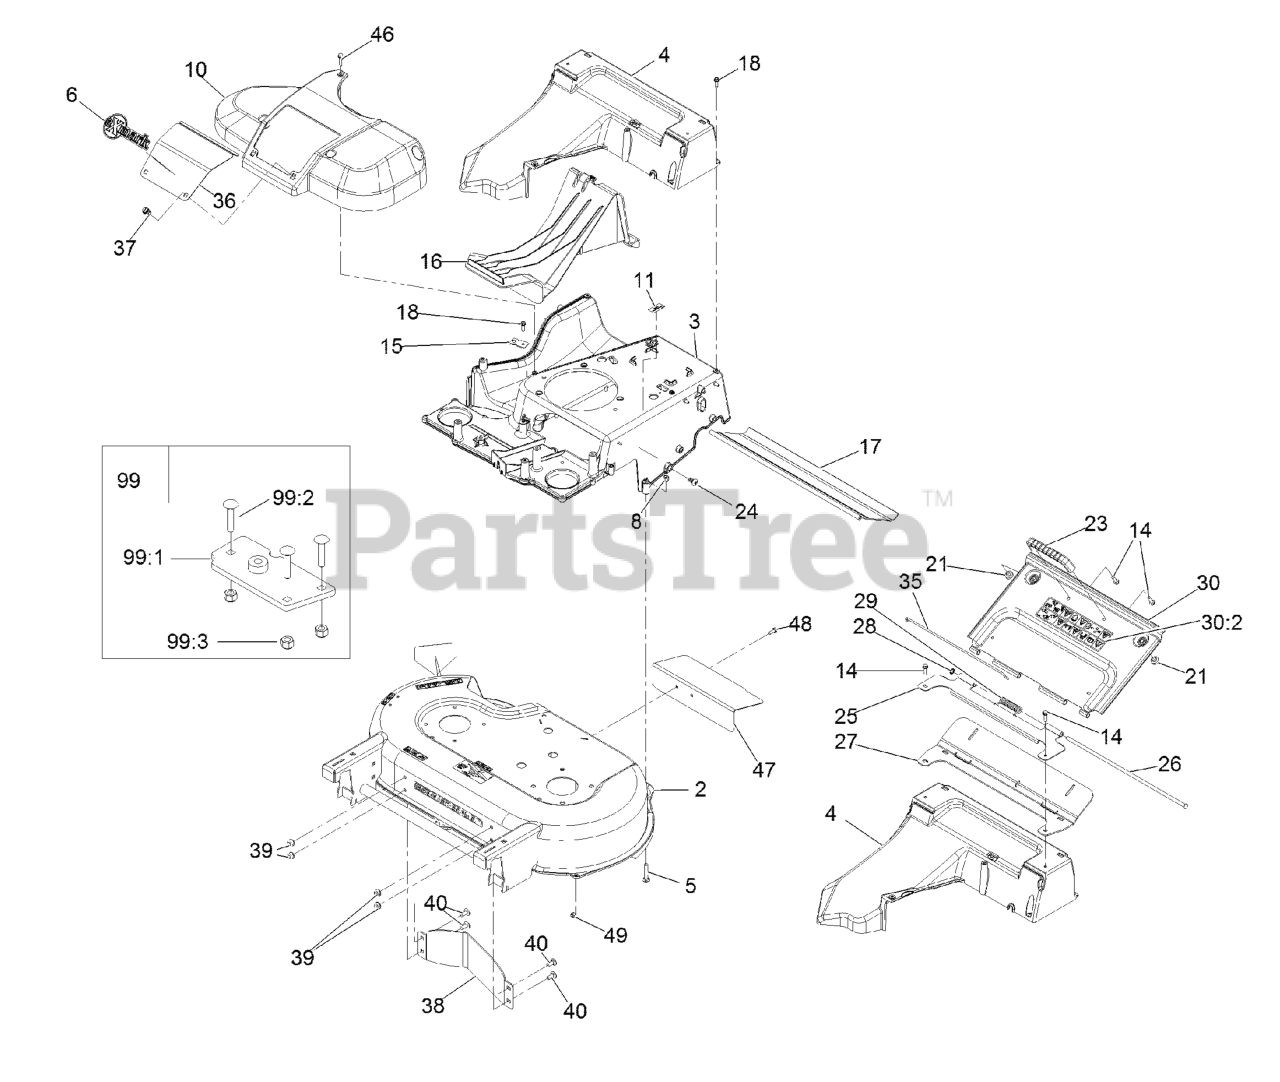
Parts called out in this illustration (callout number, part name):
2	DECK-30, W/DECALS
3	FRAME
5	BOLT-CAR
6	DECAL-EXMARK LOGO
8	NUT-LOCK, NI
10	COVER-BELT
11	Decal-Patent Ttco.Com
14	SCREW-HWH
16	PLUG-MULCH
17	SHIELD-TRAILING
18	SCREW-HWHTF
23	HANDLE-DOOR
24	SCREW-PTH
25	BRACKET-HINGE
26	PIN-HINGE
27	SEAL-DOOR
28	RING-RETAINING
29	SPRING-TORSION, COVER
30	REAR DOOR ASM
30:2	DECAL-WARNING
35	CLIP-SEAL
36	DOOR-ACCESS
37	FASTENER
38	BAFFLE-CONTROL
39	NUT-HF, NI
40	SCREW-HSBH
46	SCREW-HWHTF
